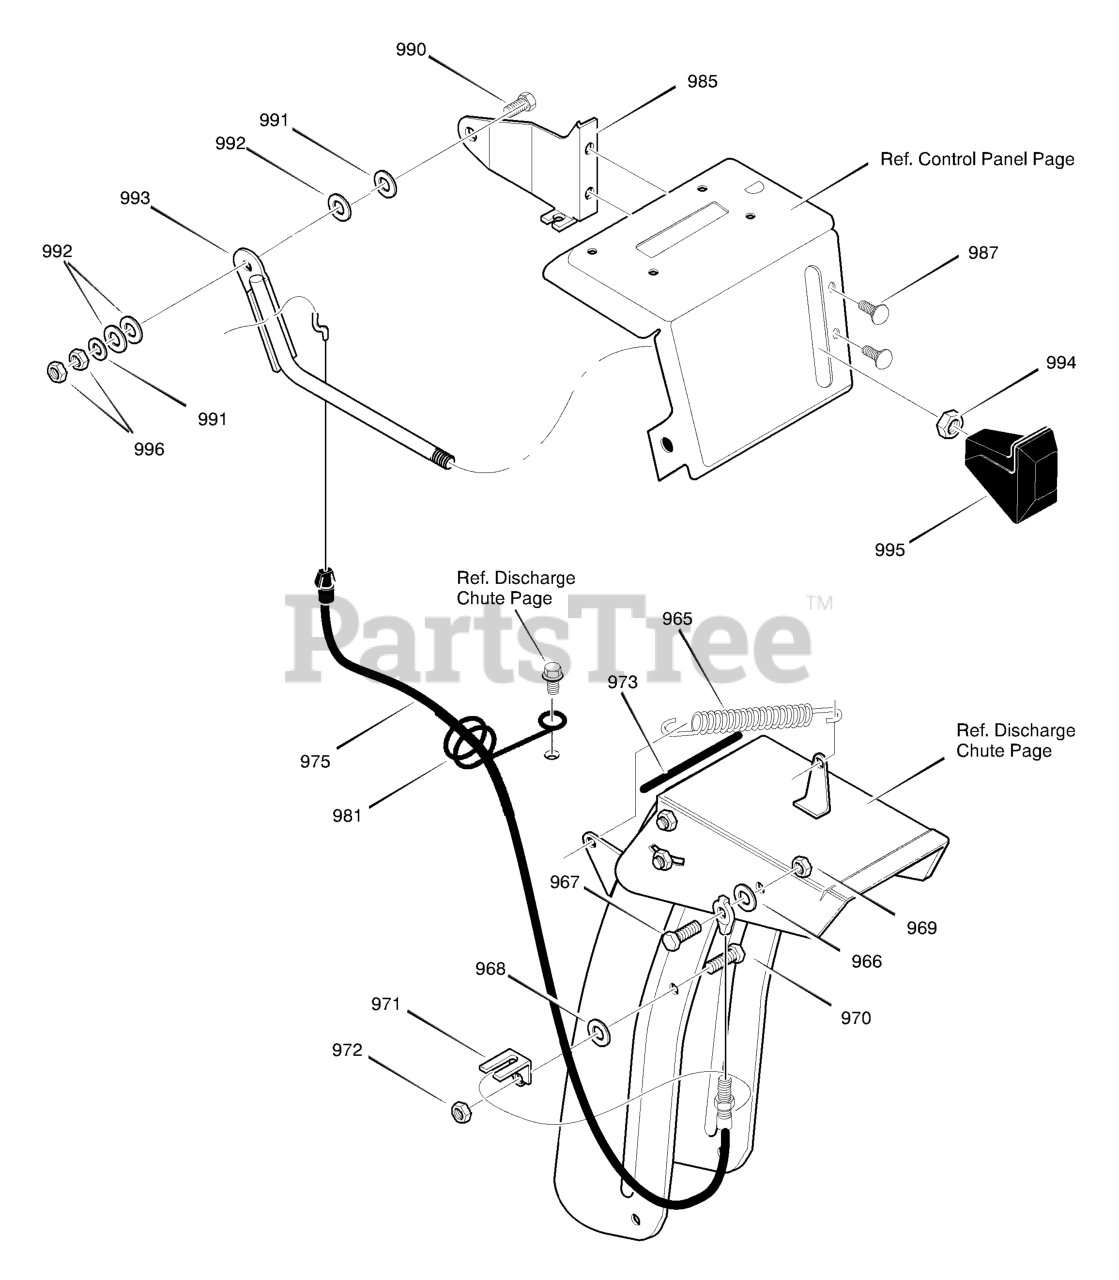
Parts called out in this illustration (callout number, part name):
965	TENSION SPRING
966	FLATWASHER
968	FLATWASHER
971	BRACKET, CABLE CHUTE
972	NUT
973	TRIM STRIP, GREY
975	CABLE, CHUTE DEFLECTOR
981	WIRE FORM, REMOTE CHUTE CABLE
985	BRACKET, SNAP-IN REMOTE
987	SCREW
990	SCREW
991	WASHER, FLAT
992	WASHER, SPRING
993	HANDLE, ASSY
995	KNOB, SHIFT
996	NUT
